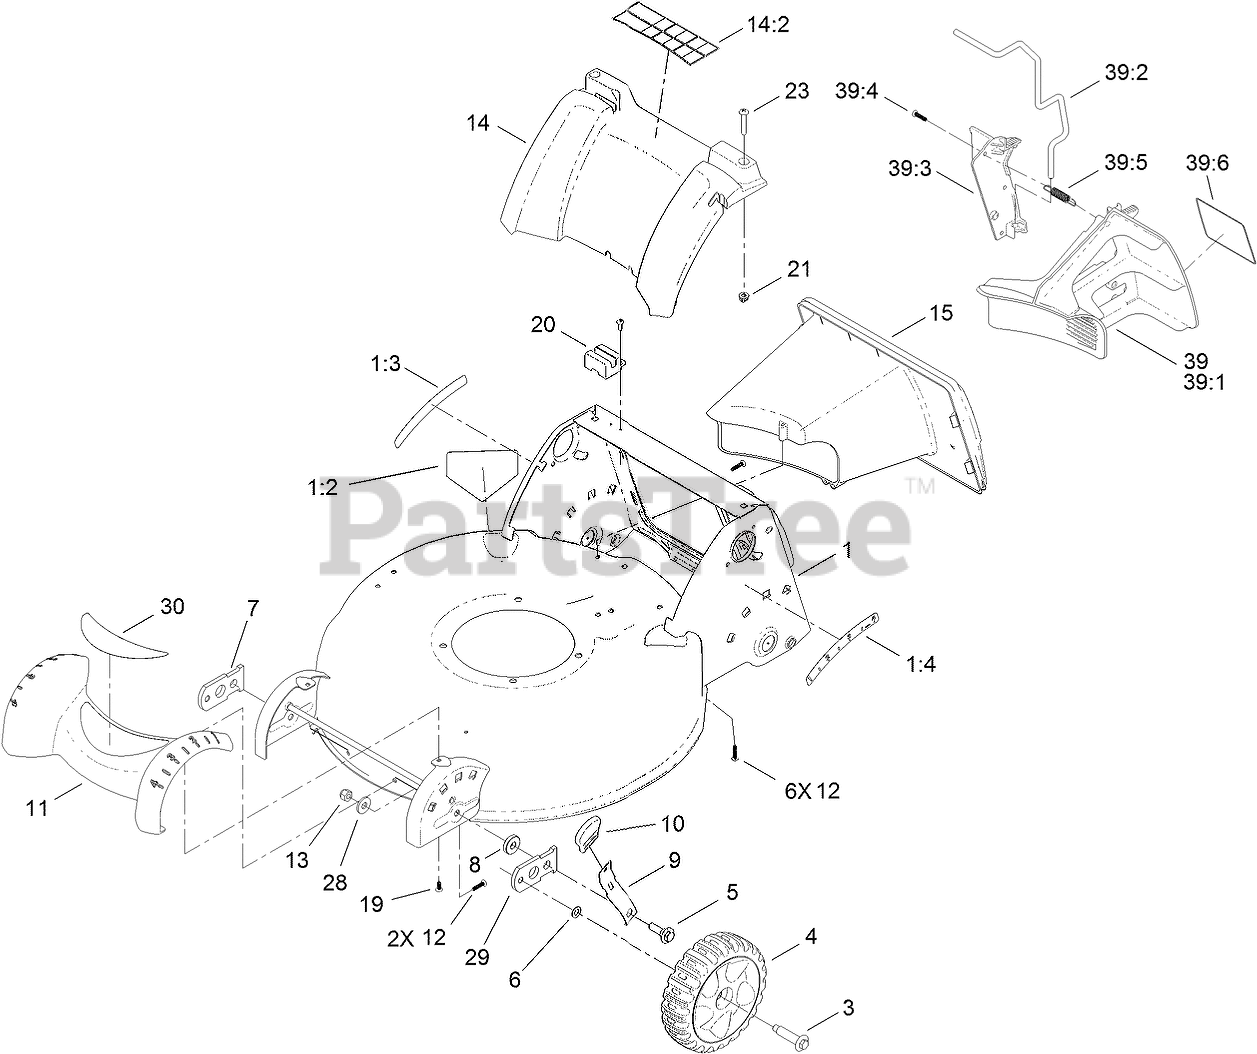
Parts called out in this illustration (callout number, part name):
1	DECK ASM
1:2	DECAL-DANGER
1:3	DECAL-HOC, RH
1:4	DECAL-HOC, LH
3	BOLT-SHOULDER
4	7 INCH WHEEL AND TIRE ASM
5	BOLT-SHOULDER
6	WASHER
7	ARM-PIVOT, RH
8	WASHER
9	ARM-SPRING
10	KNOB-HOC
11	COVER-FRONT
12	SCREW-PLASTITE
13	NUT-LOCK, NI
14	REAR COVER ASM
14:2	DECAL-WARNING
15	TUNNEL
19	SCREW-PLASTITE
20	MODULE-SWITCH
21	NUT-CLIP
23	SCREW-PTH
28	WASHER-HARDENED
29	ARM-PIVOT, LH
30	DECAL-FRONT (CE)
39	MULCH PLUG ASM
39:1	PLUG-MULCH, LH
39:2	LATCH-PLUG, MULCH
39:3	PLUG-MULCH, RH
39:4	SCREW-PLASTITE
39:5	SPRING-EXTENSION
39:6	DECAL-PLUG, MULCH
